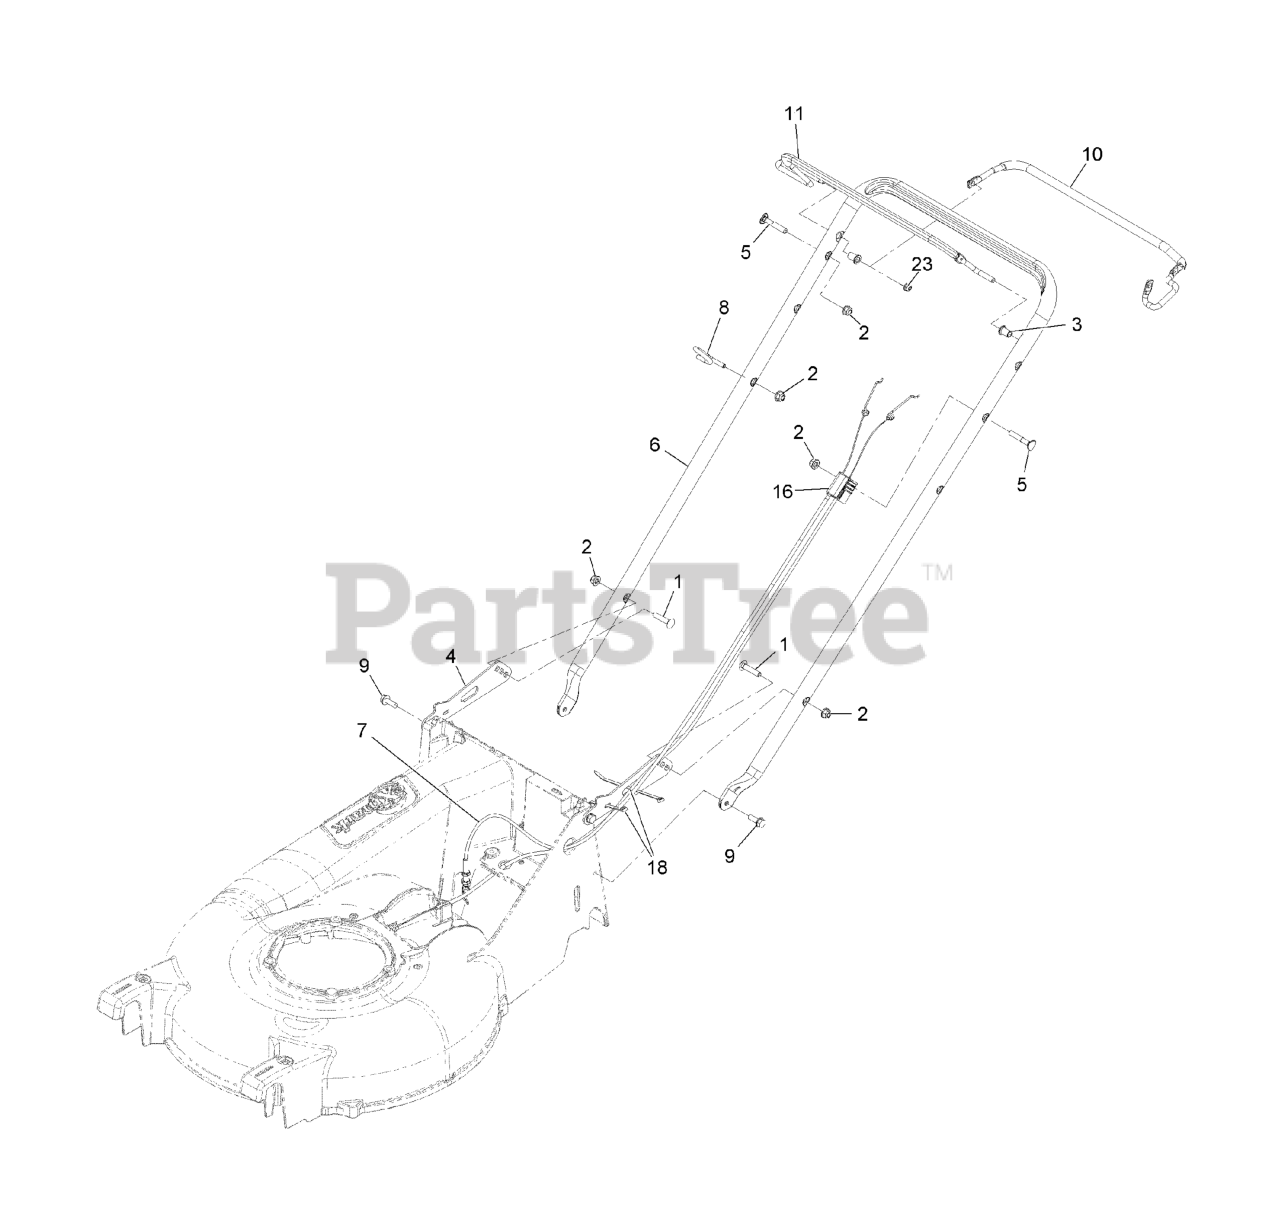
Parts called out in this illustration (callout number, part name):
1	BOLT-CARR
2	NUT-HF, NI
3	BUSHING-HANDLEBAR
4	BRACKET,HANDLEBAR
6	HANDLEBAR-P21
7	CABLE, DRIVE EC21
8	GUIDE,ROPE
9	SCREW-TAPTITE
11	BAIL,OPC/BBC
16	CABLE-ZONE KAWASAKI
18	TIE-CABLE
